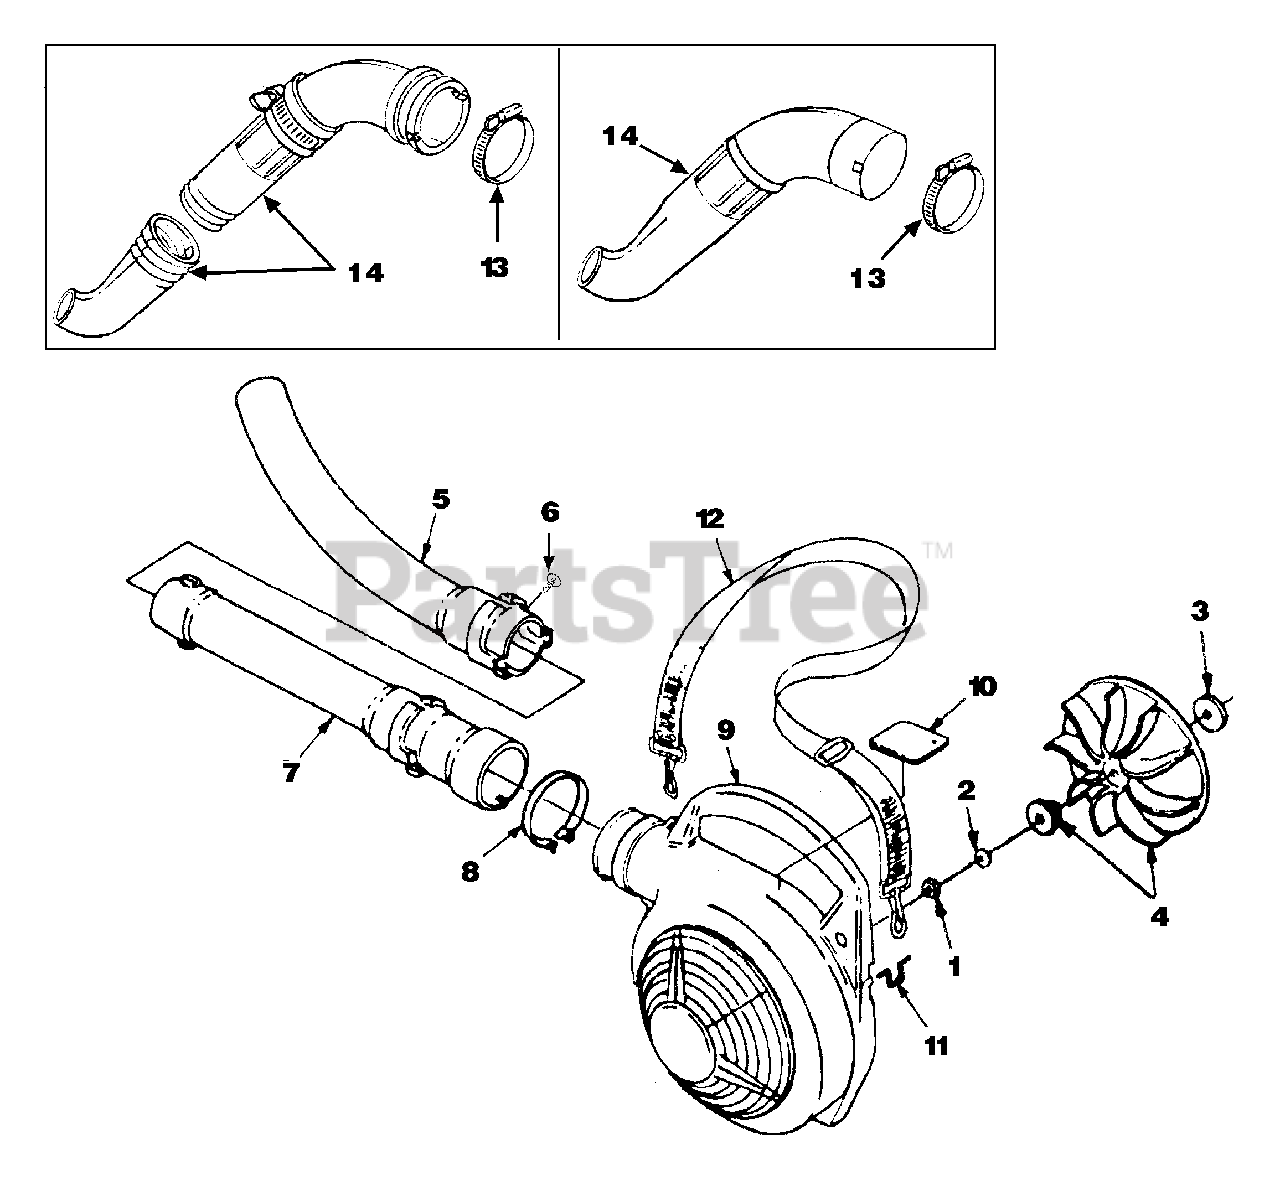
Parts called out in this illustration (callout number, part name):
1	NUT-Hex (3/8-24)
2	WASHER-Bellville (3/8")
3	WASHER-Flat
4	BLOWER FAN KIT
5	NOZZLE-Sweeper
6	CLIP - Push
7	TUBE-Upper
8	CLAMP w/Fasteners
9	VOLUTE HOUSING (Outer)
10	DECAL-Warning
11	LOOP-Wire
12	SHOULDER STRAP
14	TUBE KIT
